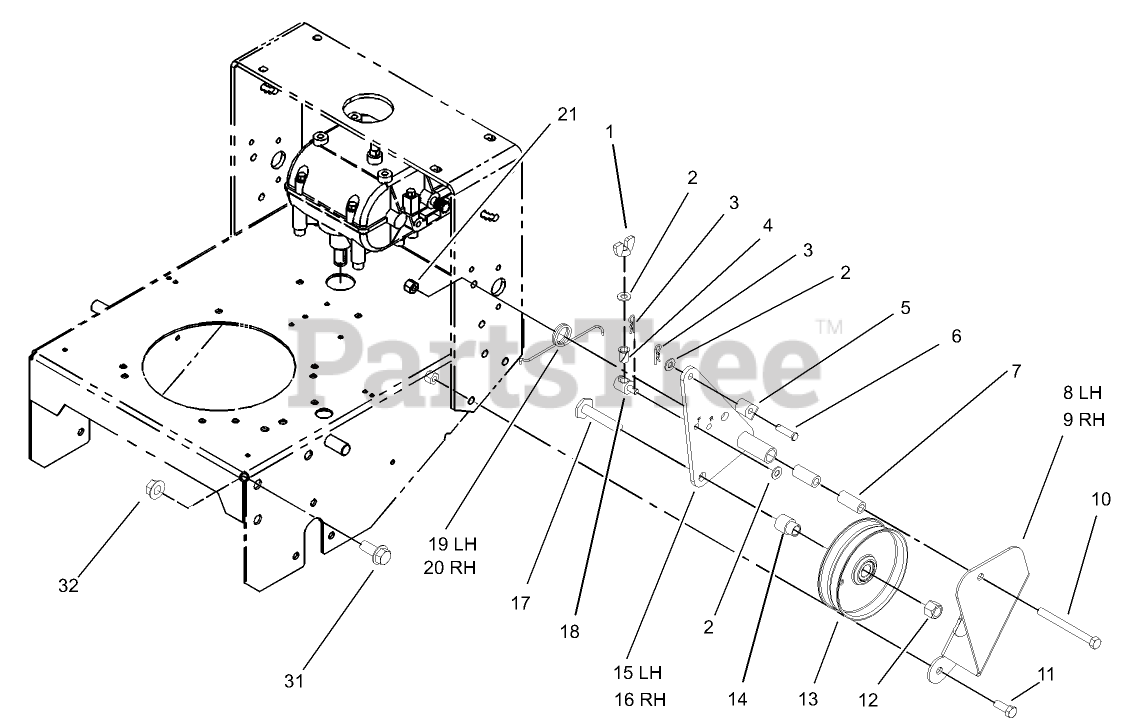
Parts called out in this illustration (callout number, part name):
1	NUT-WING
2	WASHER-PLAIN
3	PIN-COTTER
4	BUSHING-NYLON
5	FITTING-ROD
6	PIN-CLEVIS
7	SPACER-PIVOT, IDLER
8	BRACKET-SUPPORT, LH
9	BRACKET-SUPPORT, RH
10	SCREW-HH
11	SCREW-HH
12	NUT-LOCK, NI
13	PULLEY-IDLER
14	SPACER-PULLEY
15	BRACKET-IDLER, LH
16	BRACKET-IDLER, RH
17	SCREW-LEVELER
18	FITTING-ROD
19	SPRING-TORSION, LH
20	SPRING-TORSION, RH
21	NUT-LOCK, NI
31	SCREW-HHF
32	NUT-HF
